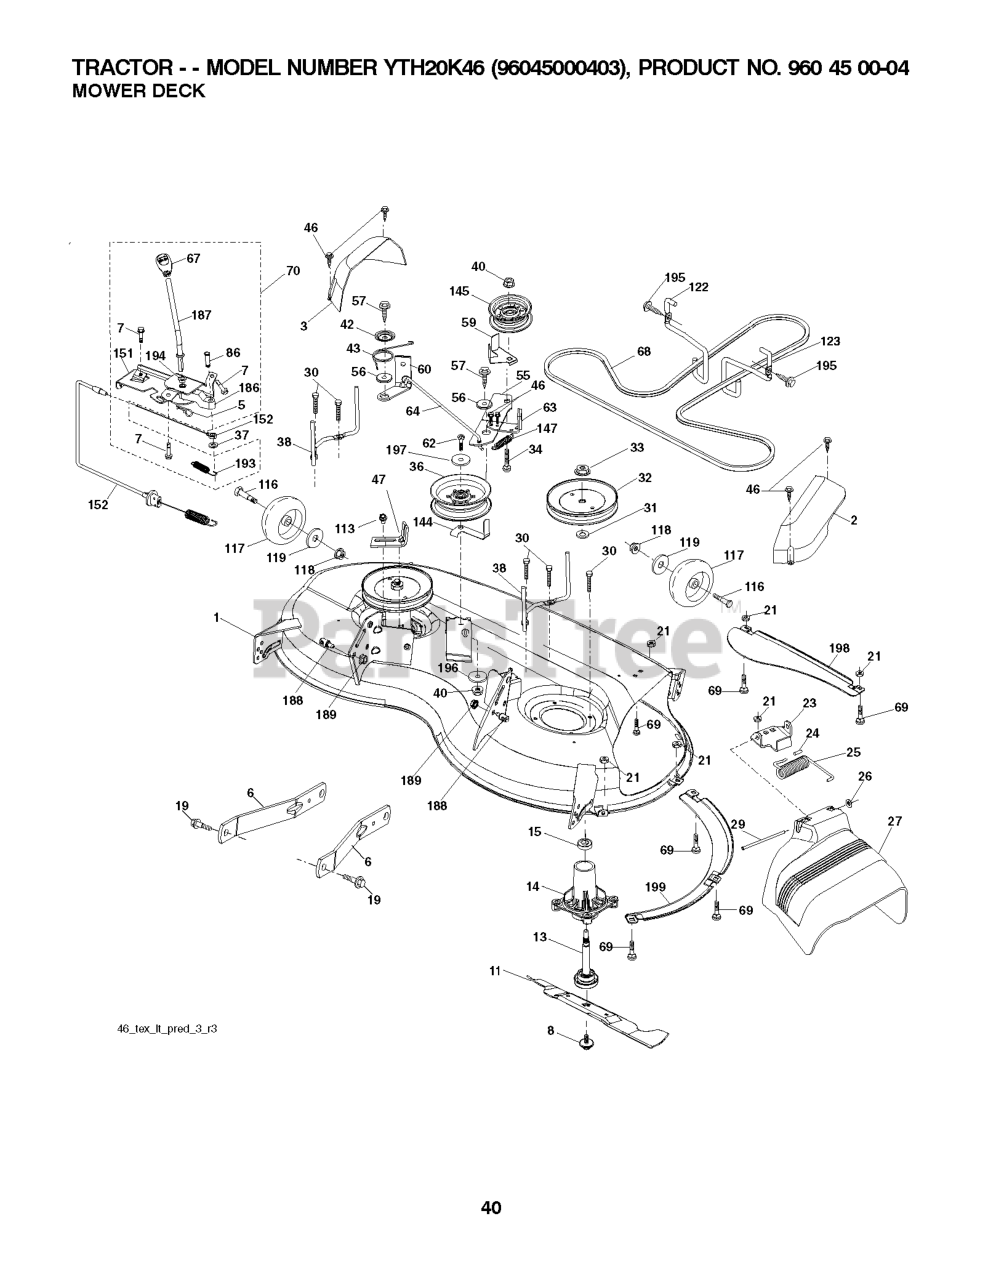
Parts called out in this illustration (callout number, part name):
1	DECK.WELDMENT.46"
2	COVER.MANDREL.RH.46"
3	COVER.MANDREL.LH.46"
5	RETAINER-SPRNG RB
6	ARM.SUSPENSION.MOWER.R
7	SCREW
8	BOLT.WASHER.ASM.7/16-2
11	BLADE.MOWER.46".HI.LIFT
13	SHAFT.ASM.MDRL.N/GREASE.38
14	RP.HOUSING.MANDREL.4PT.
19	BOLT.SHOULDER
21	LOCKNUT
23	BRKT.DEFLECTOR.38"2005+
24	CAP-SLEEVE LT
25	SPRING.TORSION.DEFLECT
26	NUT PUSH M
27	SHIELD.DEFLECTOR.MOWER.46"BLAC
29	ROD.HINGE
30	SCREW, WASHER HEAD
31	WASHER.SPACER.MANDREL
32	PULLEY.MANDREL.5.438.P
33	NUT.FLANGE.LOCK.TOP
34	BOLT.3/8-16X1.50
36	PULLEY.IDLER.2006
37	WASHER
38	KEEPER.BELT.LH.MANDREL
40	NUT LOCK FLG 3/8-16 UNC
42	SPRING.TORSION.BRAKE
43	SRPING.TORSION.RETAINE
46	SCREW.1/4-20X5/8
47	BRKT.CLUTCH.CABLE
56	SPACER.RETAINER
57	SCREW 3/8-16X1
59	GUARD, BELT
60	BRAKE.ASM.RH.38".TEX.COATED
62	BOLT-HEX EAK
63	ARM.BRAKE.ZINC
64	LINKAGE.ASM.BRAKE.CLEAR.ZINC
67	HANDLE.CLUTCH.CABLE.LT
68	V-BELT
69	BOLT
70	CLUTCH.ASM.CABLE.HUSQ.TEX
86	PIN ATTACHMENT CABLE
113	BOLT.5/16HEX.WHS.HD
116	BOLT.SHOULDER.3/8-16X3-5/8.
117	RP WHEEL. GUAGE RALLY
118	NUT LOCK FLG 3/8-16 UNC
119	WASHER
122	KEEPER BELT ENGINE LH
123	KEEPER BELT RH
144	KEEPER.BELT.MOWER
145	PULLEY.IDLER.FLAT
147	SPRING RETURN
151	BRACKET.MOUNT.CC
152	CABLE CLUTCH MANUAL W/SPR.
186	ARM ACTUATOR
187	LEVER.CONTROL.CL.CBL
188	STUD.FASTNER.W/ANTI-ROTATE
189	NUT LOCK HEX FLANGE 5/16-18
193	SPRING.PLUNGER.ACTUATOR
194	BEARING.CONTROL.LEVER.CLUTCH
195	SCREW, 3/8-16X3/4
196	WASHER.13/32 X 1 X 1/2.11GUARD
197	WASHER
198	BAFFLE CENTER FRONT
199	BAFFLE FRONT RH
